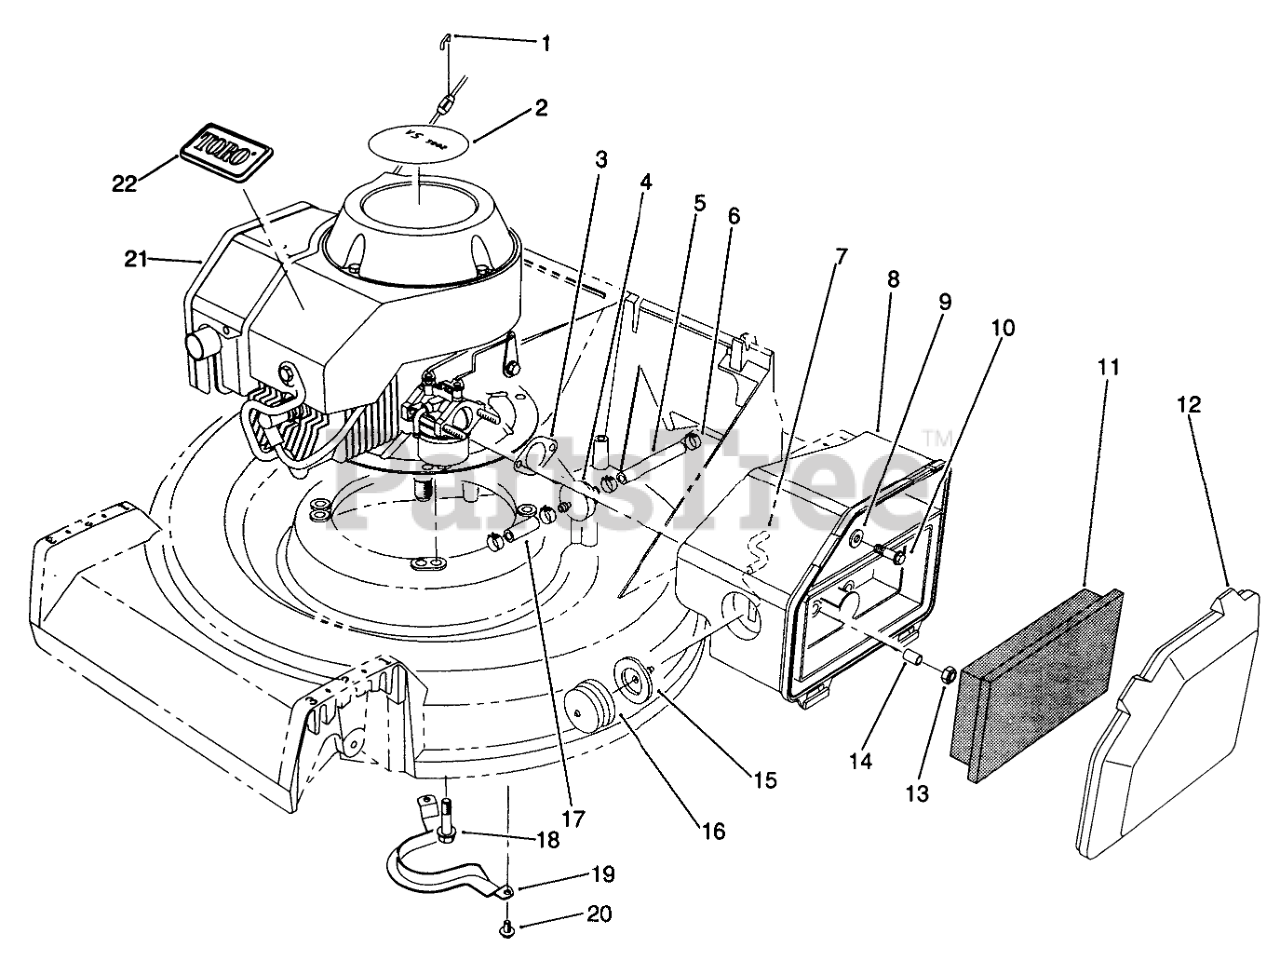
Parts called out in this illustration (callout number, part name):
1	Staple
2	DECAL-2 CYC RECOIL COMM
3	GASKET-AIR CLEANER
4	FILTER-FUEL
5	HOSE-FUEL
6	CLAMP-FUEL LINE
7	HOSE-PRIMER
8	BODY-AIR CLEANER
9	WASHER-FLAT
10	SCREW-HH
11	ELEMENT-AIR CLEANER
12	COVER-AIR CLEANER
14	SPACER
15	BODY-PRIMER
16	BULB-PRIMER
17	LINE-GAS
18	Bolt-Engine
19	Guide-Belt
20	SCREW-HWHTF
21	ENGINE ASM
22	TORO LOGO PLT
